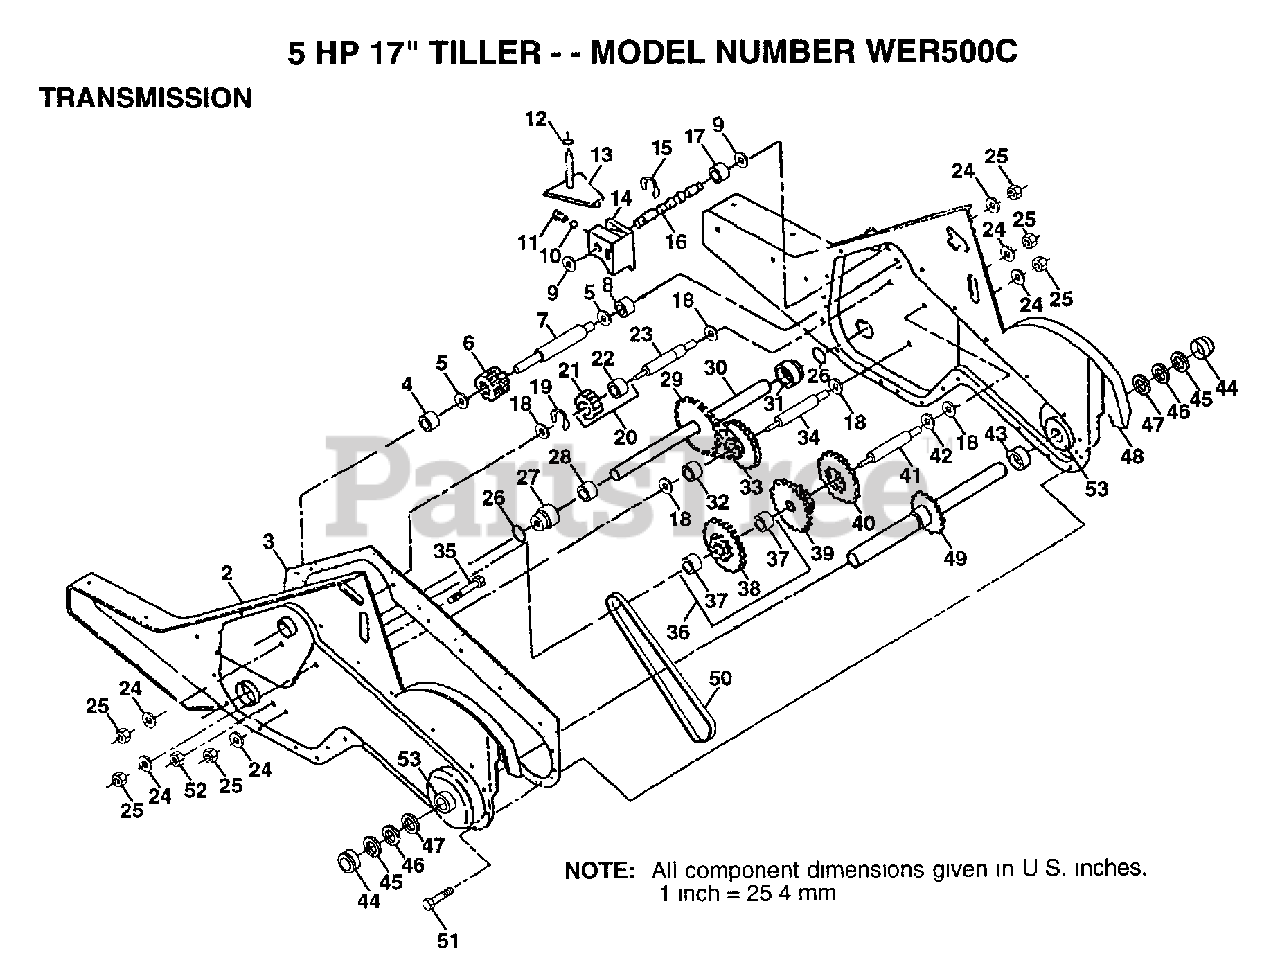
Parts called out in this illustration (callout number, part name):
3	GASKET TI
4	NEEDLE BRNG LT
5	"T, BEARING"
6	PINION-INPUT CRT
7	SHAFT-INPUT CRT
8	"TI, BEARING"
9	WASHER SEAL CRT
11	SPRING-SHIFT CRT
12	O-RING TI
13	ARM ASSY CRT
14	SHIFT FORK TI
15	KLIP RING
16	SHAFT SHIFT CRT
17	SPACER SPLIT CRT
18	WASHER
19	KLIP RING
20	GEAR ASSY CRT
21	GEAR-REV IDLR CRT
22	NEEDLE BEARING TI
23	SHAFT CRT
24	LOCKWASHER
25	NUT.ASF.HEX.7/16
26	O RING CRT
27	"CRT, BEARING"
28	BUSHING TI
29	CHAIN CRT
32	SPACER TI
33	SPRCKT 8 GEAR CRT
34	SHFT 2ND RED. CRT
35	SHAFT CRT
36	SPROCKET ASM.
37	BEARING
39	GEAR TI
40	GEAR TI
41	REDUCTION SHFT TI
42	BRNG RACE
43	SPACER TI
44	CUP.FORMED.
45	RING SPIRAL CRT
46	SEAL RING RUBBER
47	OIL SEAL STD
49	TINE SHAFT
50	CHAIN.50 LINK TI
51	SCREW CRT
52	NUT.HEX.5/16-18
